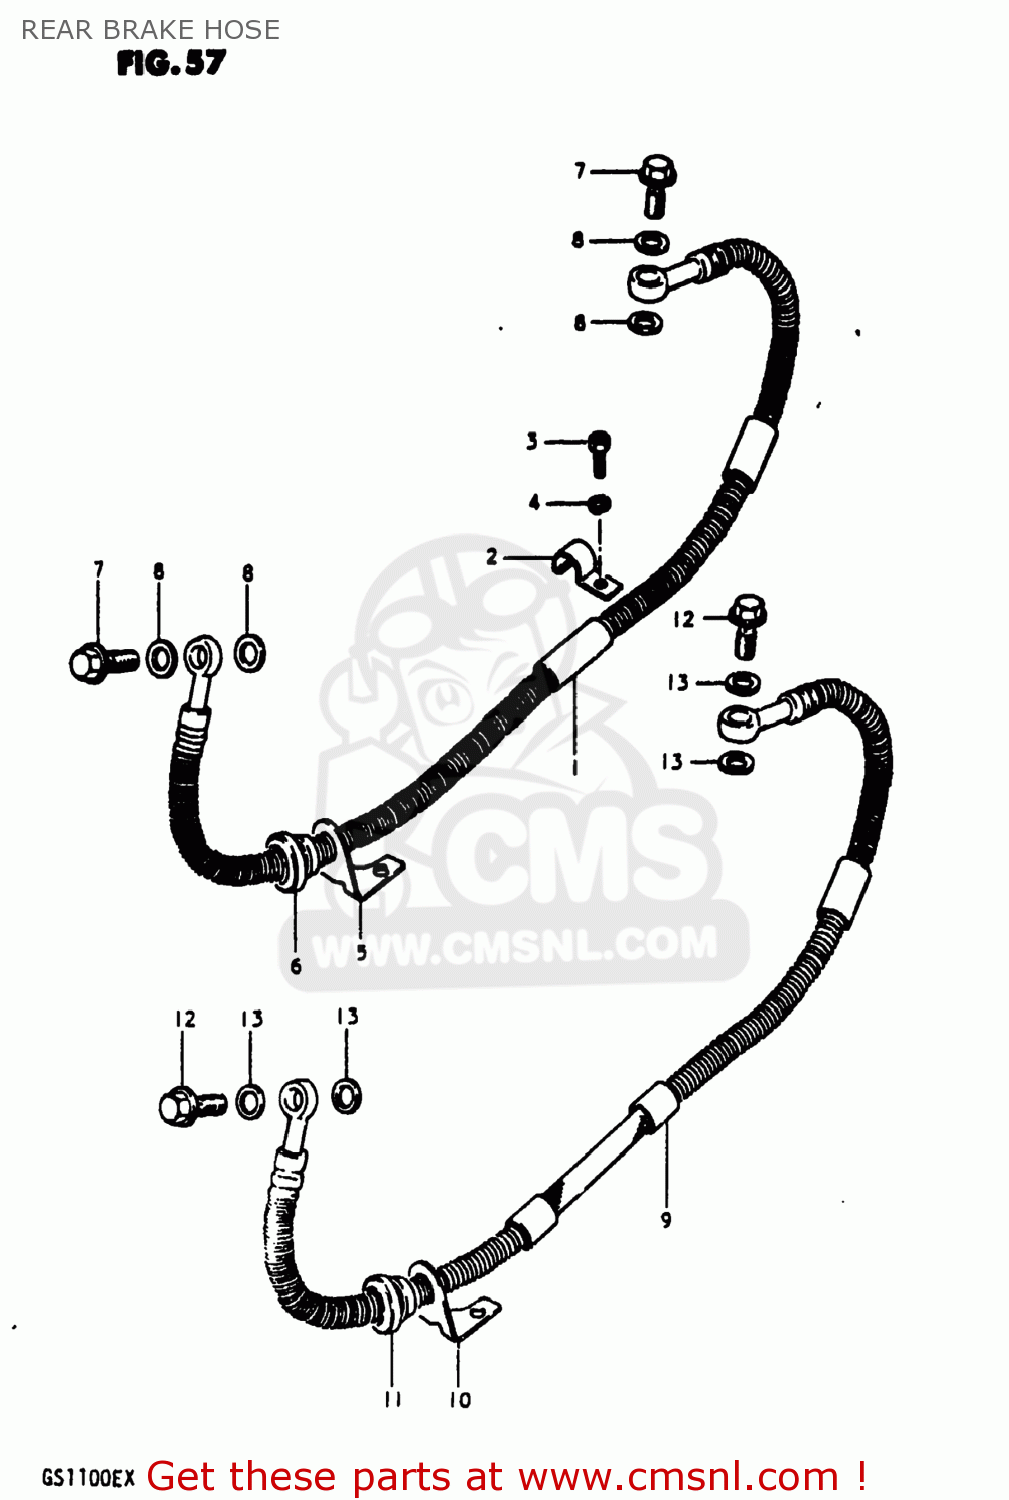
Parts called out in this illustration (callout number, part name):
1	HOSE,REAR BRAKE
2	CLAMP,REAR BRAKE HOSE
3	SCREW(6X8)
4	LOCK WASHER
5	GUIDE,BRAKE HOSE
6	GROMMET,BRAKE HOSE GUIDE
7	BOLT,UNION
8	WASHER
9	HOSE,REAR BRAKE
10	GUIDE,BRAKE HOSE
11	GROMMET,BRAKE HOSE GUIDE
12	BOLT,UNION
13	WASHER
